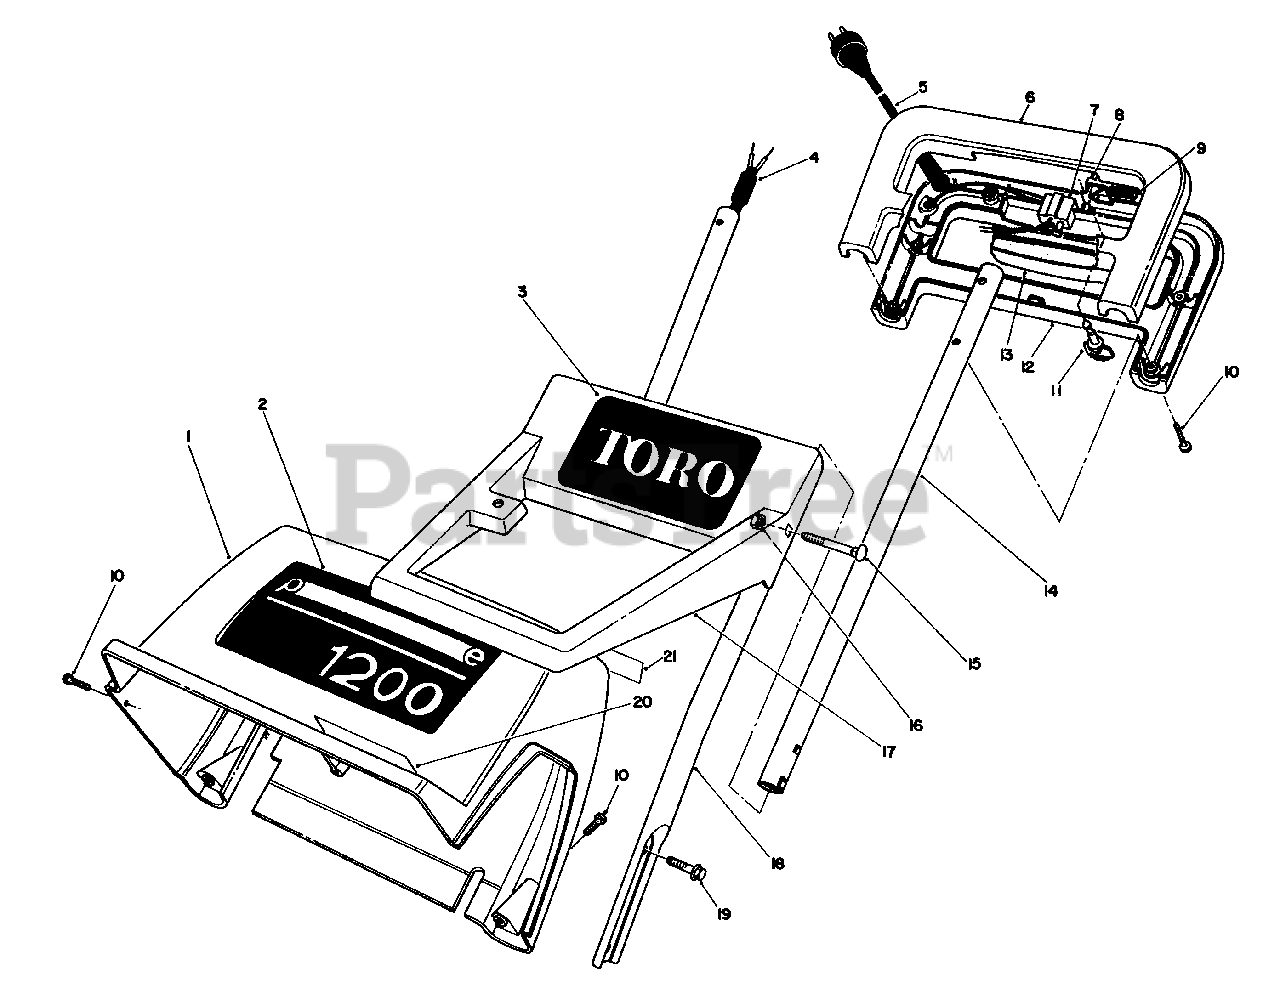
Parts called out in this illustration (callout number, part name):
1	Shroud (Incl. Ref. #2, 20, & 21)
2	Decal-1200
3	Decal-Toro
4	Wire Harness
5	Cord Supply
6	Handle-Upper Control
7	Switch-Starter
8	Switch-Lockout
9	Spring-Compression
10	Screw-Self Tap. Pan Hd.
12	Handle-Lower Control
13	Bar-Switch
14	Tube-Upper
15	Bolt-Carriage
16	Nut-Lock
17	Handle-Middle
18	Handle-Lower L.H.
19	Screw
20	Decal-Danger
21	Decal-U.L.
